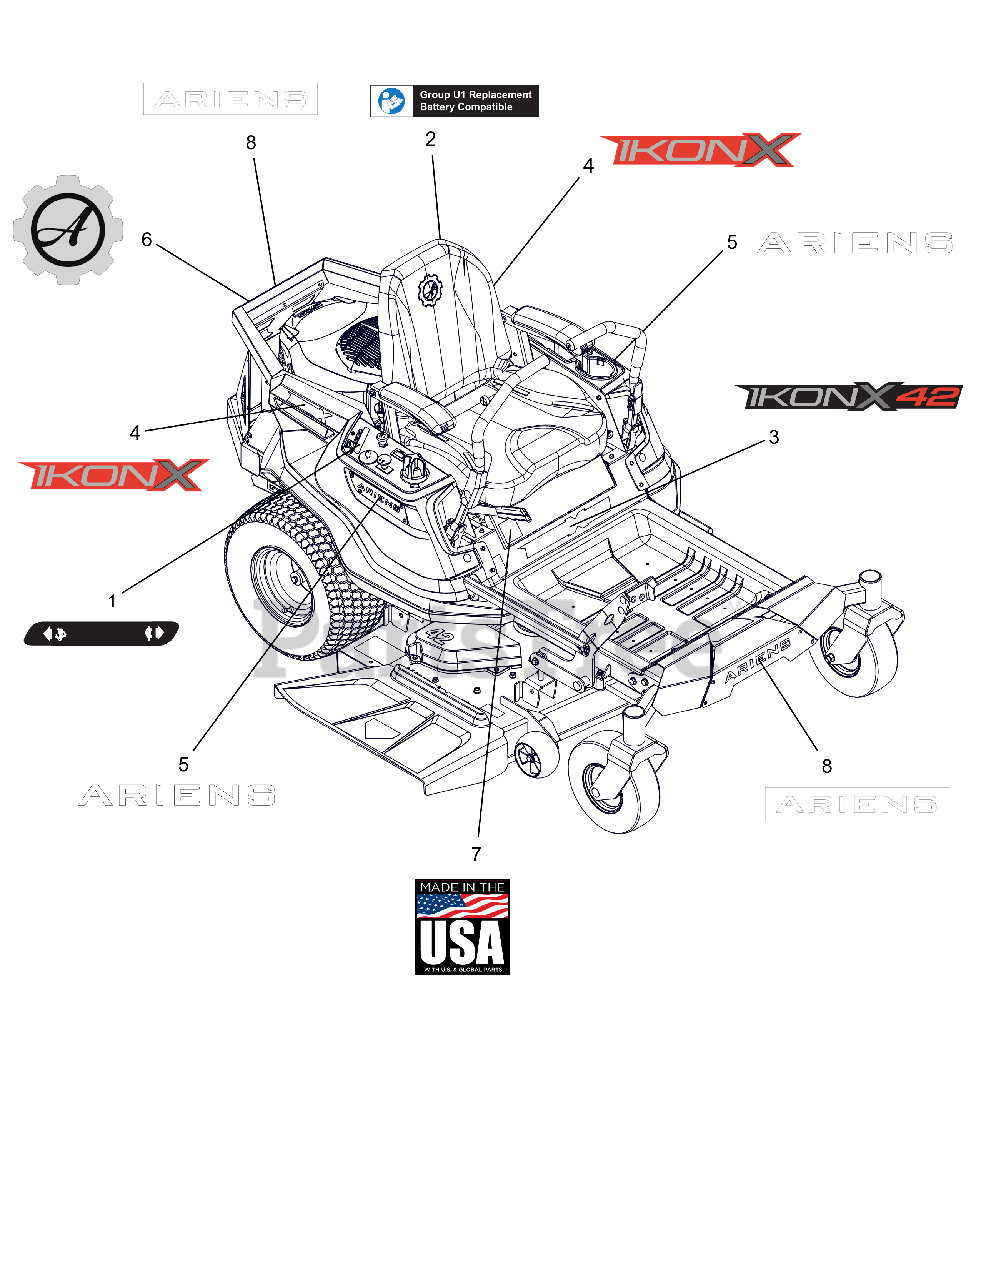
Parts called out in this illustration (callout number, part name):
1	DECAL, DASH DECAL
2	DECAL, U1 BATTERY REPLACEMENT
3	DECAL, IKON-X 42"
4	DECAL, IKON
5	DECAL, ARIENS (6.50")
6	DECAL, ARIENS-GEAR BADGE
7	DECAL, MADE IN USA
8	DECAL - ARIENS 9.625"
